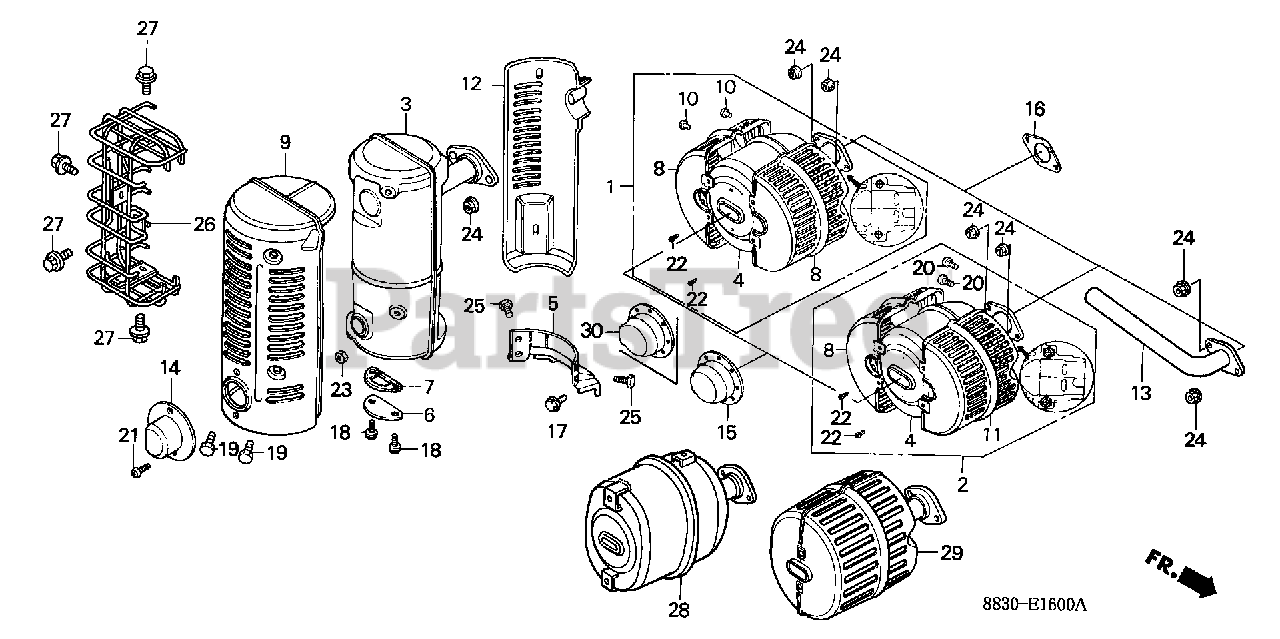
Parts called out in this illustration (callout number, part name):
1	MUFFLER ASSY. (CHROME PLATED) Use up to Engine SN 1012894.
1	MUFFLER ASSY. (CHROME PLATED)
2	MUFFLER ASSY. (CHROME PLATED)
3	MUFFLER (MUFFLER LID)
4	MUFFLER Use up to Engine SN 1428861.
4	MUFFLER
5	STAY, MUFFLER
6	LID, MUFFLER
7	GASKET, MUFFLER LID
8	PROTECTOR, L. MUFFLER Use up to Engine SN 1012894.
8	PROTECTOR, L. MUFFLER
9	PROTECTOR A, MUFFLER
10	RIVET (4X5)
11	PROTECTOR, R. MUFFLER (NOT AVAILABLE)
12	PROTECTOR B, MUFFLER
14	DEFLECTOR, EX. MUFFLER
15	CAP, MUFFLER
16	GASKET, MUFFLER
17	BOLT, FLANGE (8X16)
18	BOLT, HEX. (6X12)
19	BOLT, HEX. (6X6)
20	SCREW, PAN (4X6)
22	SCREW, TAPPING (4X8)
23	NUT, HEX. (4MM)
24	NUT, FLANGE (8MM)
25	BOLT, FLANGE (6X10)
